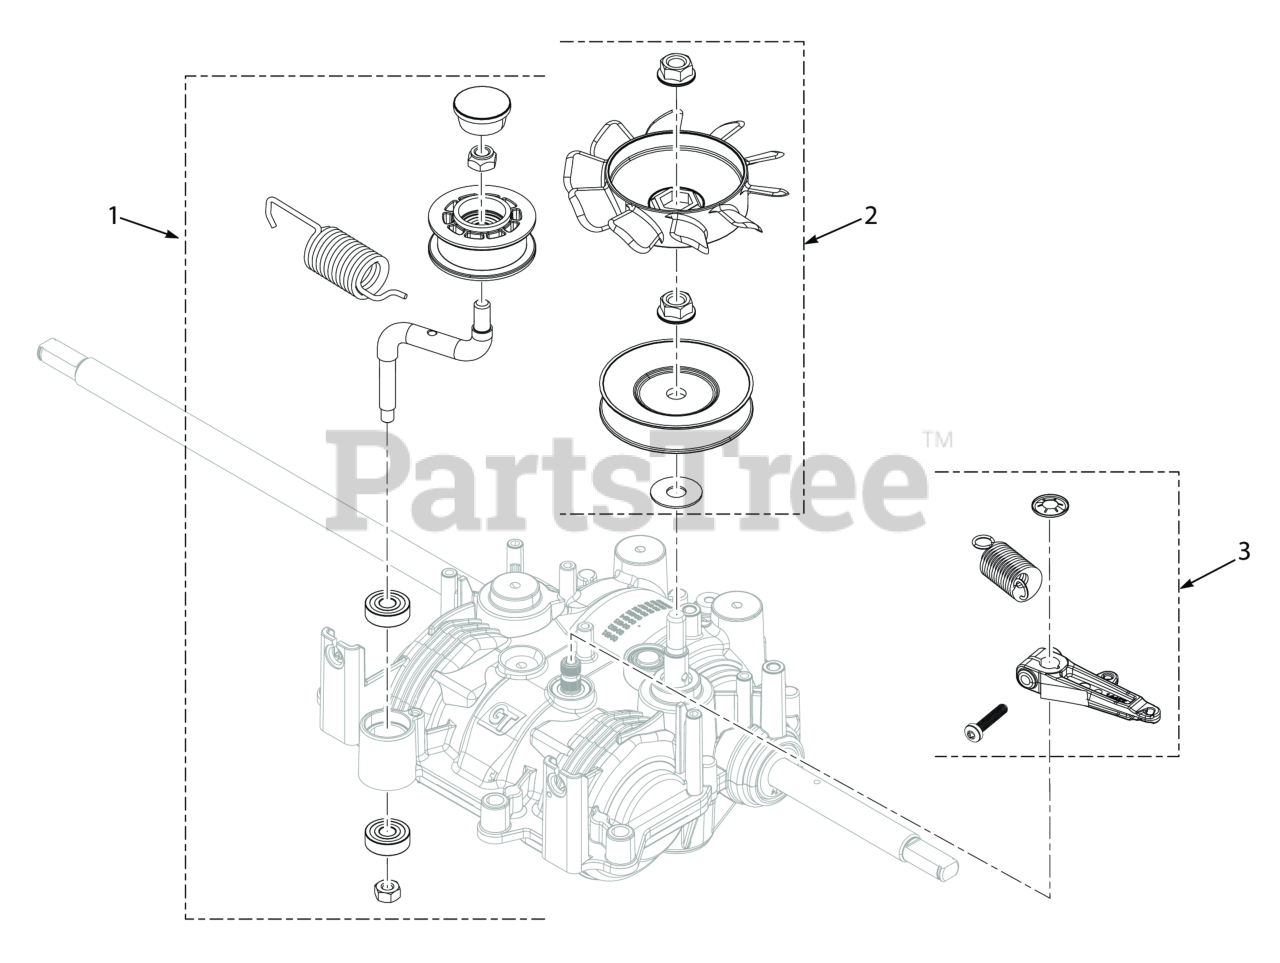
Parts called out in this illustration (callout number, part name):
1	Transmission Service Kit, Idler Assembly
2	Transmission Service Kit, Pulley & Fan Assembly
3	Transmission Service Kit, Clutch Lever Assembly
